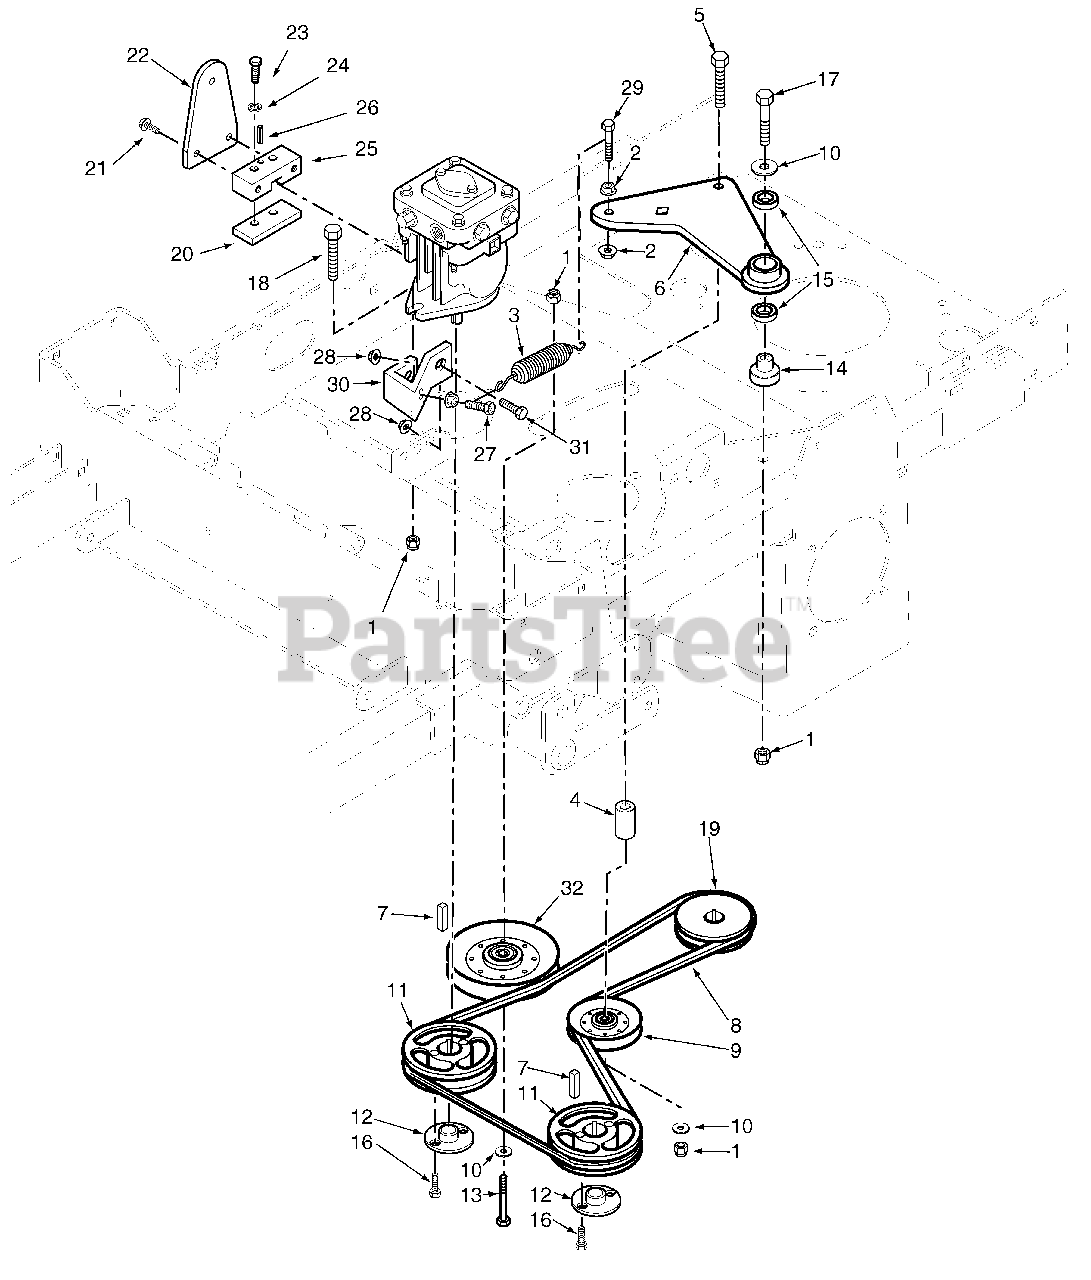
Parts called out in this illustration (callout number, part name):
1	Nut, Elastic Stop 3/8-16
2	Nut, Serrated Flange 3/8-16
3	Spring, Pump Idler
4	Spacer
5	Bolt, Hex Head 3/8-16 x 2-3/4"
6	Idler Arm Assy., Pump Drive
7	Key, 5 x 5 x 25mm
8	Belt, Transmission
9	Pulley, 3-1/2" Dia. Idler
10	Flatwasher, 3/8-.391 x .938 x .105
11	Pulley, 5.75 OD Taper Bore
12	Hub, Tapered, 15mm Bore
13	Bolt, 3/8-16 x 2"
14	Pivot, Idler
15	Bearing
16	Bolt, Hex Head 1/4-20 x 1" Grade 8
17	Bolt, Hex Head 3/8-16 x 2-1/2"
18	Bolt, Hex Head 3/8-16 x 1-1/2"
19	Pulley, 5.75 Dia. - 1.125" Bore
20	Clamp Plate
21	Hex Head Capscrew, 1/4-20 x 3/4"
22	Control Lever, Pump
23	Hex Head Capscrew, 1/4-20 x 3/4"
24	Lockwasher, 1/4"
25	Block, Pump Control
26	Roll Pin
27	Bolt, Hex Head 3/8-16 x 1-1/2" Grade 8
28	Nut, Serr. Flange 3/8-16
29	Bolt, Hex Head 3/8-16 x 1-1/2" Grade 8
30	Bracket
31	Bolt, Hex Head 3/8-16 x 1"
32	Pulley, 5" Dia. Idler
